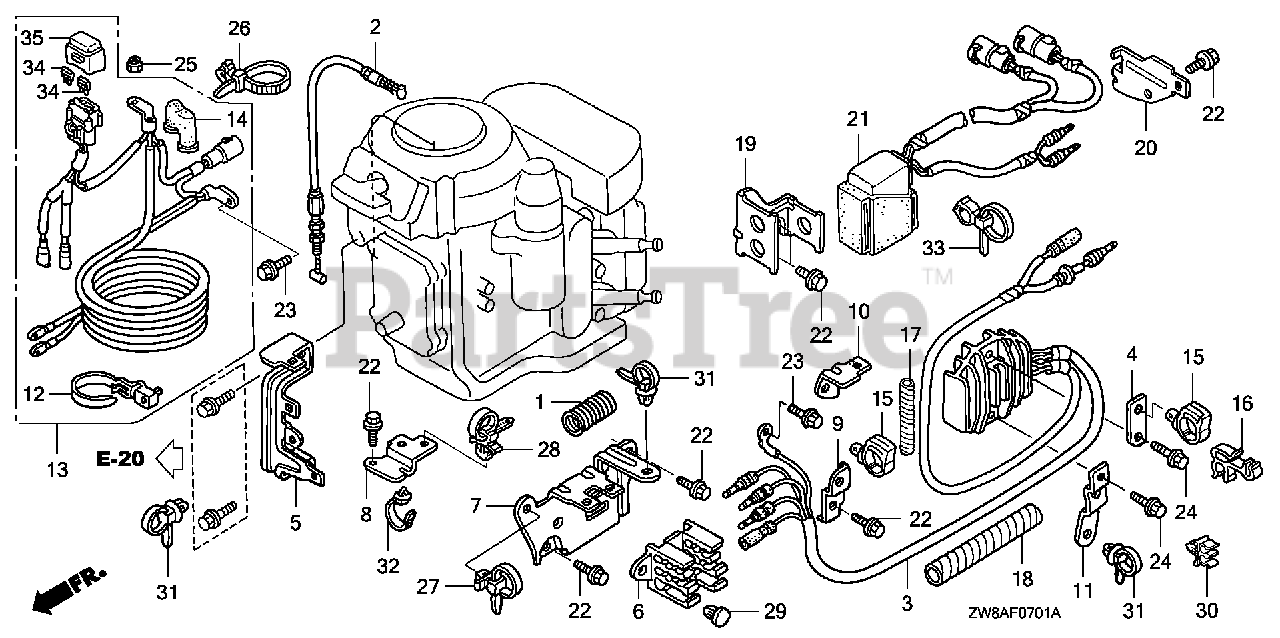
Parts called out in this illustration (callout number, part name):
2	CABLE, NEUTRAL STARTING
3	RECTIFIER ASSY., REGULATOR
4	BRACKET, CLIP F
5	BRACKET, CONNECTOR A
6	BRACKET, CONNECTOR (B)
7	BRACKET, CONNECTOR
8	BRACKET, STARTER CABLE
9	BRACKET, CLIP B
10	BRACKET, FUSE CASE
11	BRACKET, E-CLIP
12	BAND, WIRE
13	CABLE ASSY., STARTER (R/C PT)
14	COVER, MAGNETIC SWITCH TERMINAL
15	CLAMP, ENGINE SUB-WIRE
16	CLAMP, DISTRIBUTOR WIRE
17	TUBE, SPIRAL C
18	TUBE, SPIRAL A
19	BRACKET, POWER TILT RELAY
20	BRACKET, CONNECTOR A
21	RELAY ASSY., POWER TILT
22	BOLT, FLANGE (6X14) (CT200)
23	BOLT, FLANGE (6X12)
24	BOLT, FLANGE (6X26) (CT200)
25	NUT, LOCK (6MM)
26	BAND, WIRE (95MM)
27	STRAP, CABLE (118MM) (BLACK)
28	STRAP, CABLE (105MM) (BLACK)
29	CLIP, ANCHOR
30	CLIP, FUEL TUBE
31	CLIP, HARNESS BAND (151.5MM) (NATURAL)
32	BAND, WIRE HARNESS (123.5MM) (BLUE)
33	CLIP, TUBE (135MM) (BLACK)
34	FUSE, BLADE (20A)
35	COVER ASSY., FUSE (20A)
